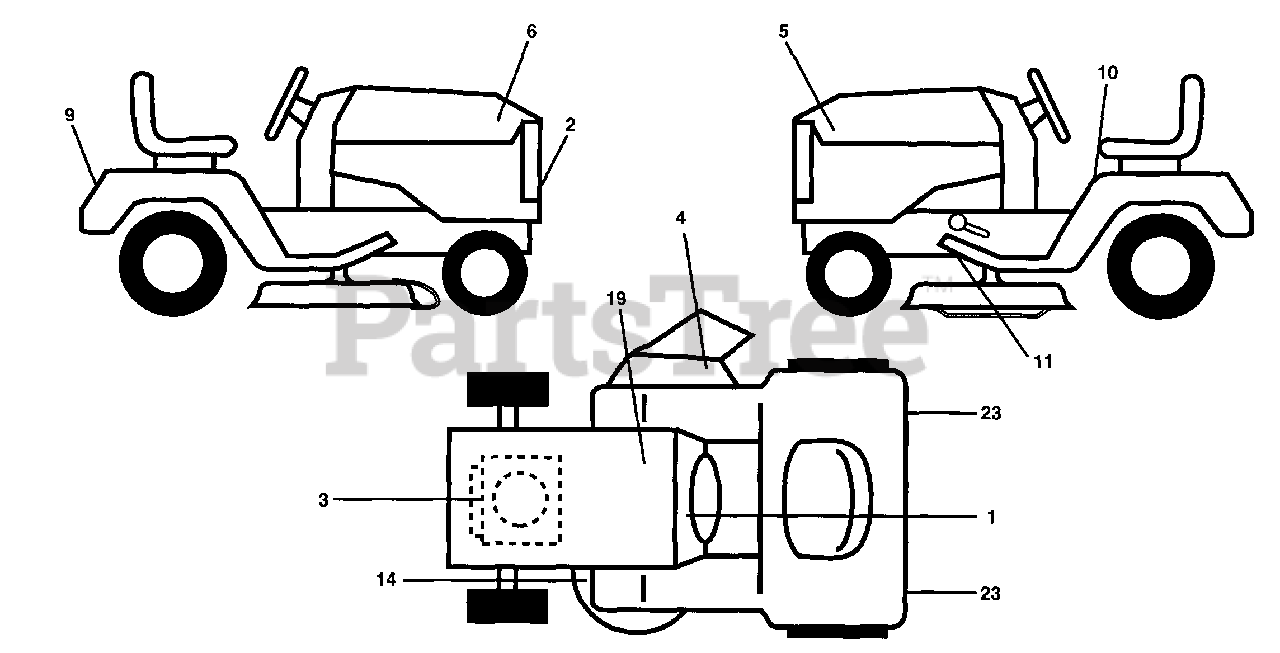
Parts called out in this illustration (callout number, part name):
1	Decal, Operating Instruction
2	Decal, Grille Husqvarna
3	Decal, Kohler
4	Decal, Warning Mult-Lang.
5	Decal, Hood LH GT200
6	Decal, Hood RH GT200
9	Decal, Fender
10	Decal, Danger
11	Decal, Clutch/Brake
14	Decal, V-Belt Schematic
19	Decal, Battery
23	Reflector, Taillight
